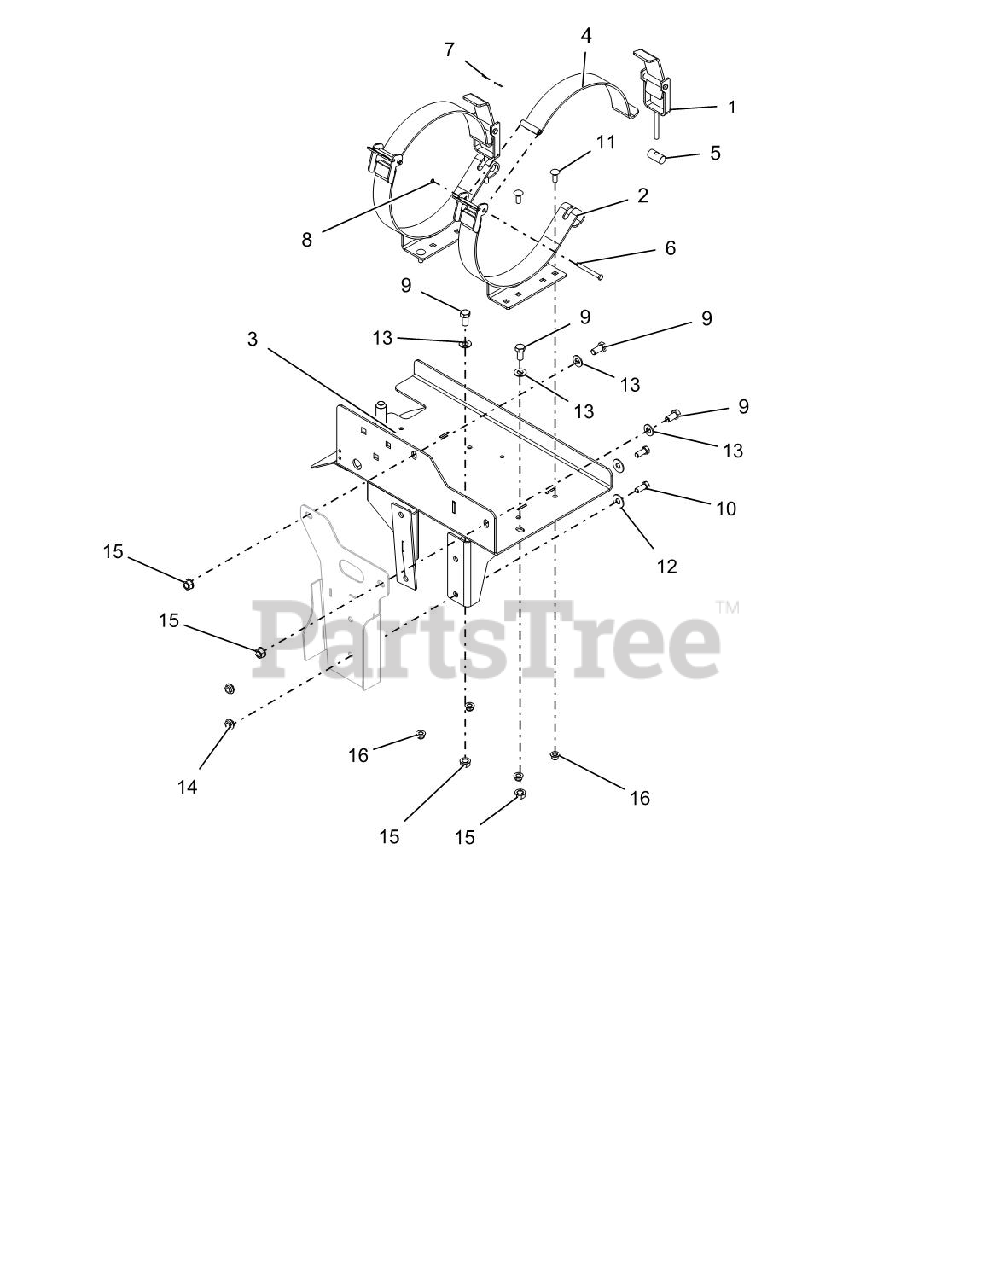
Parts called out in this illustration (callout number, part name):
1	ASM,TOGGLE CLAMP
2	WLDMT, CLAMP LP TANK
3	LH LP TANK MTG W/SAFETY DECAL
4	LP TANK CLAMP W/SAFETY DECAL
5	PIVOT, LP CLAMP HANDLE
6	PIN, LP CLAMP
7	MAGNET, .75X.06, LP CLAMP
8	RG-RTNG-EXT .312X.025
9	BLT-HEX .50-13X1.00 GR5 YWZC
10	BLT-HEX .44-14X1.00 GR5 YWZC
11	BLT-RDHDSQNK .38-16X1.00 G5YZ
12	WSHR-FL-STL.50X1.25X.083 YWZC
13	WSHR-FL-STL.531X1.06X.095YWZC
14	NUT-LK-NYL-FLG .44-14 YWZC
15	NUT-LK-TOP-FLG .50-13 YWZC
16	NUT-LK-NYL-FLG .38-16 YWZC
